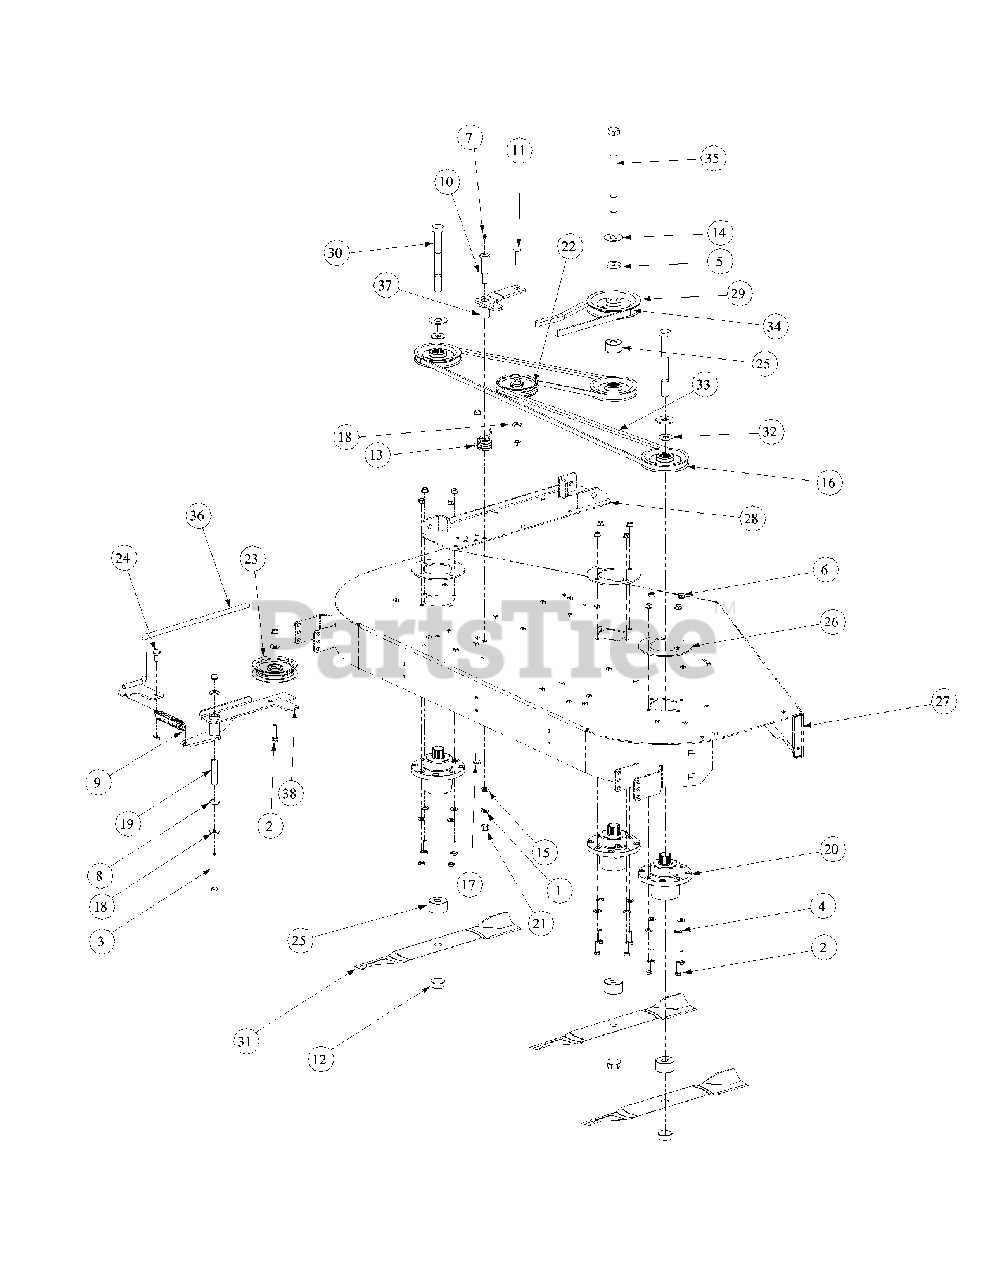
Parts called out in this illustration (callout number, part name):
1	Lock Washer, 7/16
2	Hex Cap Screw, 3/8-16 x 1-1/2
3	Hex Cap Screw, 3/8-16, 3.75
4	Flat Washer, 3/8
5	Caster Spacer
6	Flange Lock Hex Nut, 3/8-16
7	Grease Fitting, 1/4-28 x 3/16
8	Idler Washer
9	Extension Spring, 1.0 x OD x 5.125
10	Shoulder Screw, 7/16-14
11	Hex Carriage Screw, 3/8-16, 1.75
12	Flange Hex Nut, 3/4-16
13	Torsion Idler Spring
14	Flat Washer, .781 ID 2.00 OD, .105
15	Flat Washer, .469 ID, .875 OD, .105
16	V-Pulley, 4.65 OD
17	Carriage Bolt, 3/8-16 x 1
18	Flat Washer, .406 ID, 1.0 OD, .105
19	Spacer, .39 ID x .625 OD x 2.75
20	Aluminum Spindle Assembly
21	Hex Nut, 7/16-14
22	Flat Pulley
23	Idler Pulley, 4.06 OD
24	Shoulder Screw, .50 x .27 Lg., 3/8-16
25	Spacer, .760 ID x 2.00 OD x 1.1
26	Aluminulm Spindle Support Plate
27	60 Deck Assembly
28	Left Hand Mount Deck Bracket Assembly
29	V-Pulley, 5.774 OD
30	Hex Cap Screw, 3/4-16, 7.00
31	Hi-Lift Blade, 21.0, 0.756 ID
32	Spacer .812 ID x .268 LG
33	V-Belt, A Section x 122.3
34	V-Belt, B Section x 91.2
35	Hex Cap Screw, 3/4-16, 9.00
36	Spring Tension Rod Assembly
37	Idler Arm Assembly, Deck Spindle
38	Idler Arm Assembly, Flat Top Bearing
38	Bearing Sleeve
